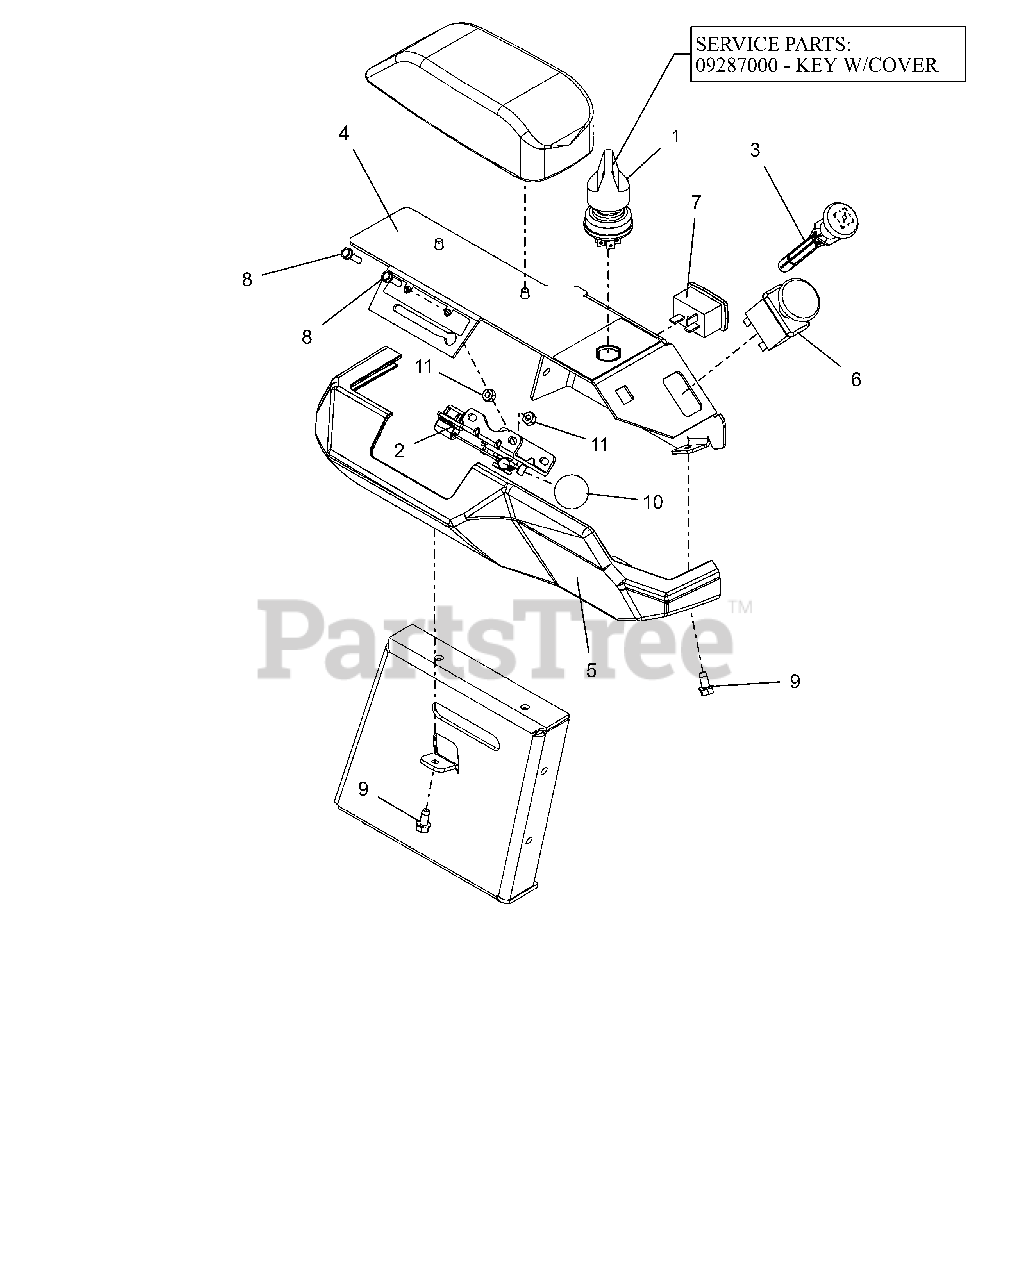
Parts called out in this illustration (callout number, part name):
1	SWITCH, IGNITION
1	KEY, W/ SHIELD
2	CABLE, PRO-CTRL 35.50"
3	CABLE, CHOKE (SNAP IN)
4	PANEL, CONTROL
5	COVER, CONTROL PANEL
6	SWITCH, CLUTCH
7	METER, HOUR W/MAINTENANCE
8	BLT, HWH #10-24X.75 ZCC
9	SCR-TAP .25-20X.50 HWH ZCC
10	KNOB-CONTROL-BLACK .38-16X.50
11	NUT-LK-NYL #10-24 G2 ZCC
